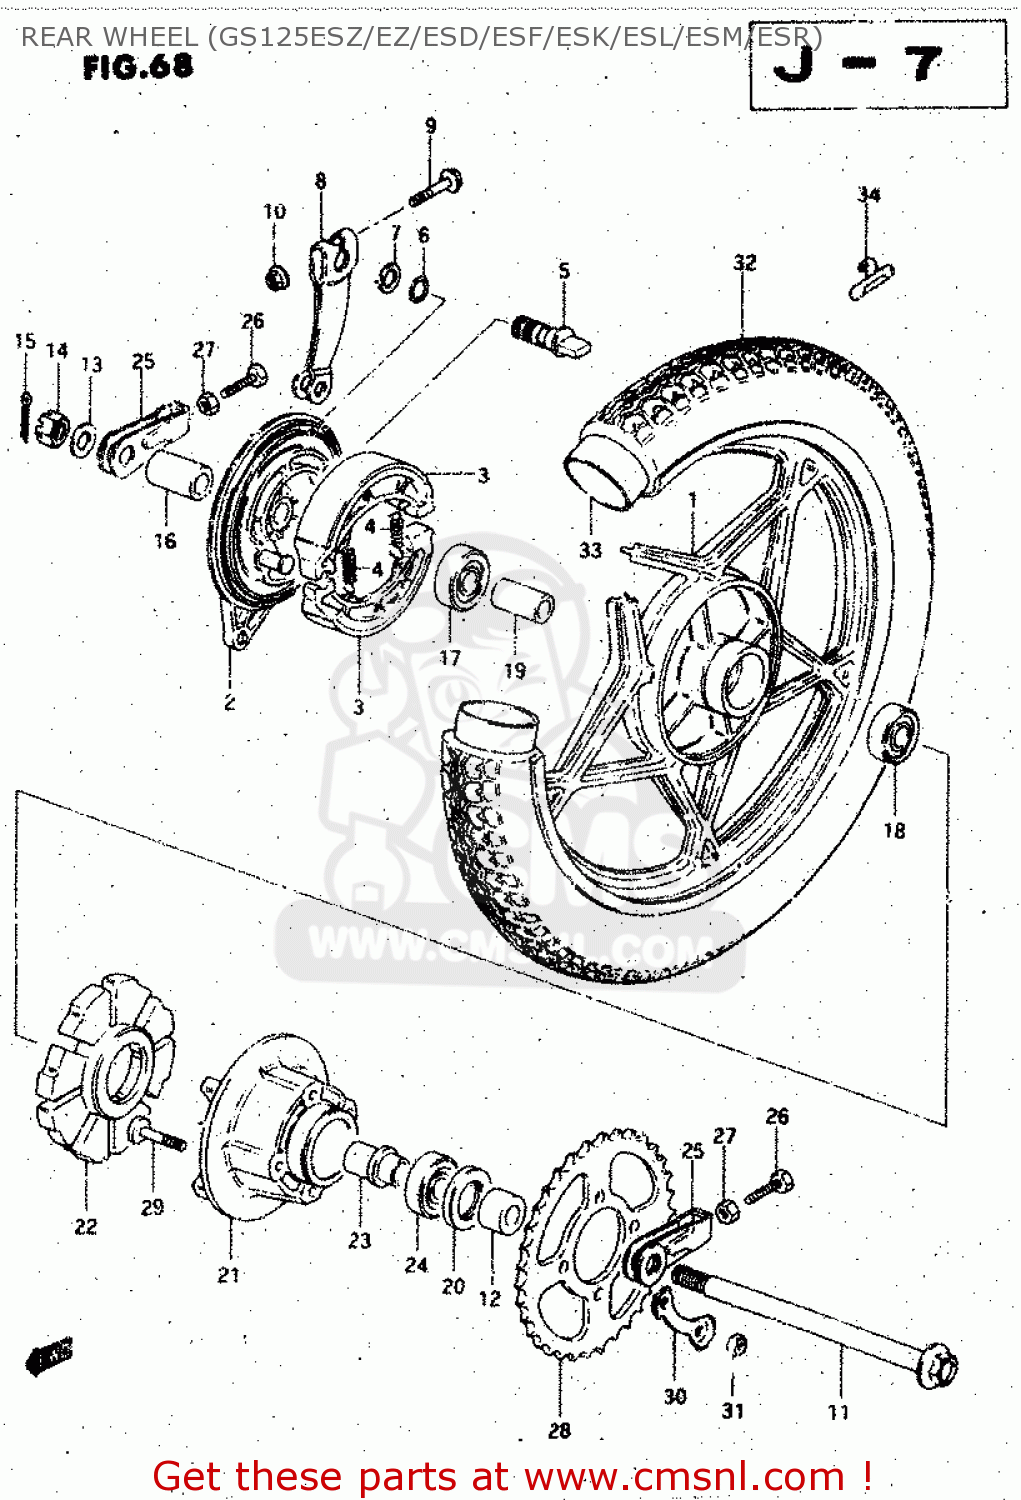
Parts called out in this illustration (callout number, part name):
1	WHEEL, REAR (MT1.85X18) (GOLD)
2	PANEL,RR BRAKE ANCHOR
3	SHOE,BRAKE
4	SPRING(L:34)
5	CAM,BRAKE
6	O-RING (D:2.4 ID:13.8)
7	WASHER (14.5X22X1.6)
8	LEVER,RR BRAKE CAM
9	BOLT
10	NUT
11	AXLE,RR
12	SPACER(15X28X19)
13	WASHER
14	NUT
15	COTTER PIN
16	SPACER(15.2X26X33)
17	BEARING
18	BEARING
19	SPACER(15.3X21.7X63)
20	SEAL,OIL(28X47X7)
21	DRUM,RR SPROCKET MOUNTING
22	ABSORBER ASSY,HUB SHOCK
23	RETAINER,RR SPROCKET DRUM
24	BEARING(20X47X14)
25	ADJUSTER,CHAIN
26	BOLT(8X50)
27	NUT
28	SPROCKET,REAR
29	BOLT
30	WASHER
31	NUT
32	TIRE
33	TUBE,INNER
34	BALANCER,WHEEL
